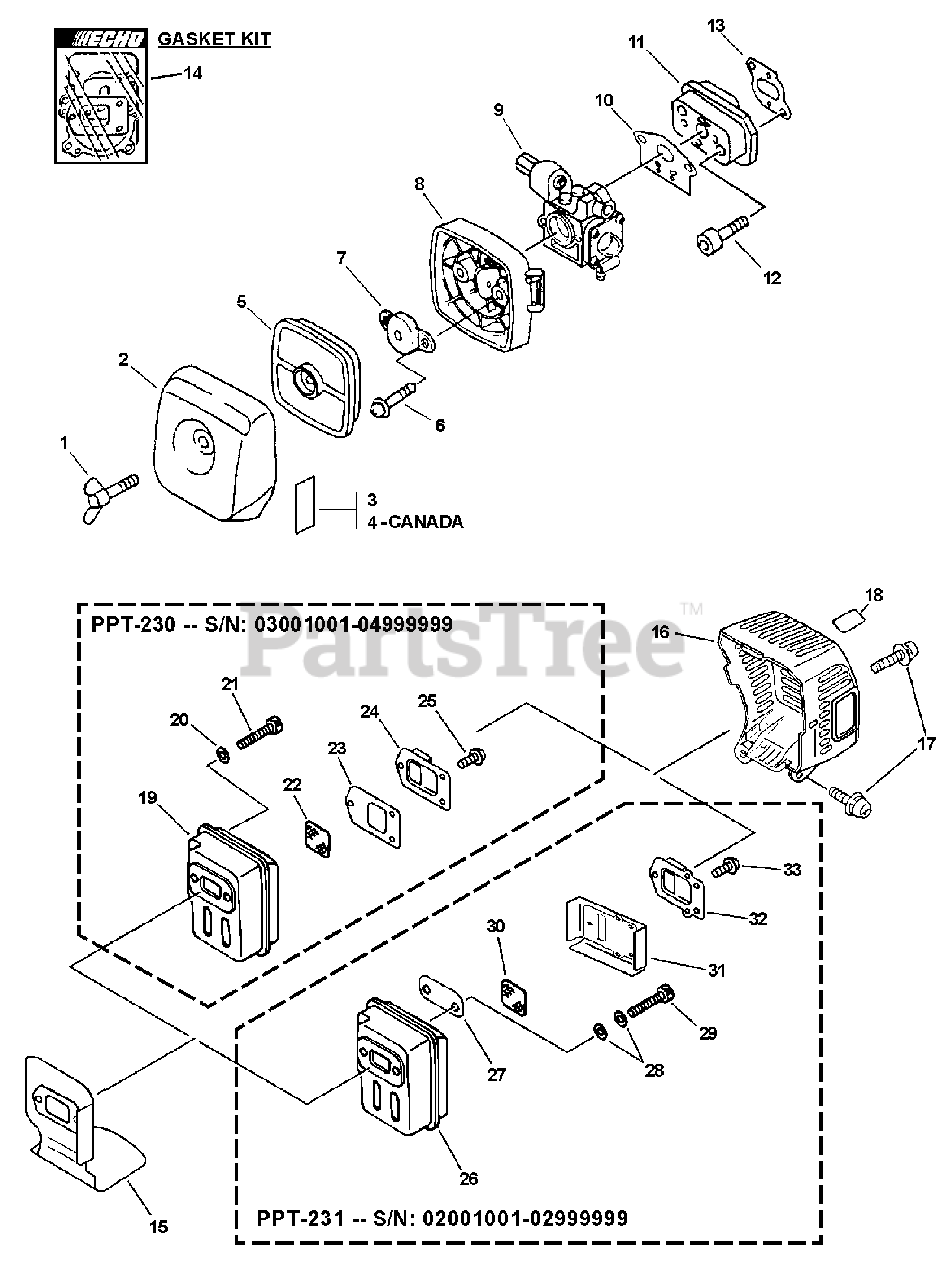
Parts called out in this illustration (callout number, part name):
1	THUMBSCREW
2	COVER, AIR FILTER - BLACK
3	LABEL - CHOKE
4	LABEL - CHOKE
5	FILTER, AIR - SINGLE LAYER
6	SCREW - 5X60
7	PLATE, PREVENT
8	CASE, AIR FILTER - BLACK
9	CARBURETOR RB-K57A
10	GASKET, INTAKE
11	INSULATOR, INTAKE
12	SCREW - 5X25
13	GASKET, INTAKE
14	GASKET KIT
15	SHIELD, EXHAUST
16	COVER, EXHAUST
17	SCREW - 5X12
18	LABEL - HOT SURFACE
20	WASHER - 5
21	SCREW - 5X55
22	SCREEN, SPARK ARRESTOR
23	GASKET, EXHAUST
24	GUIDE, EXHAUST
25	SCREW - 4X12
26	MUFFLER
28	WASHER - CONICAL
29	SCREW - 5X55
30	SCREEN, SPARK ARRESTOR
31	GASKET, EXHAUST
32	GUIDE, EXHAUST
33	SCREW - 4X10
